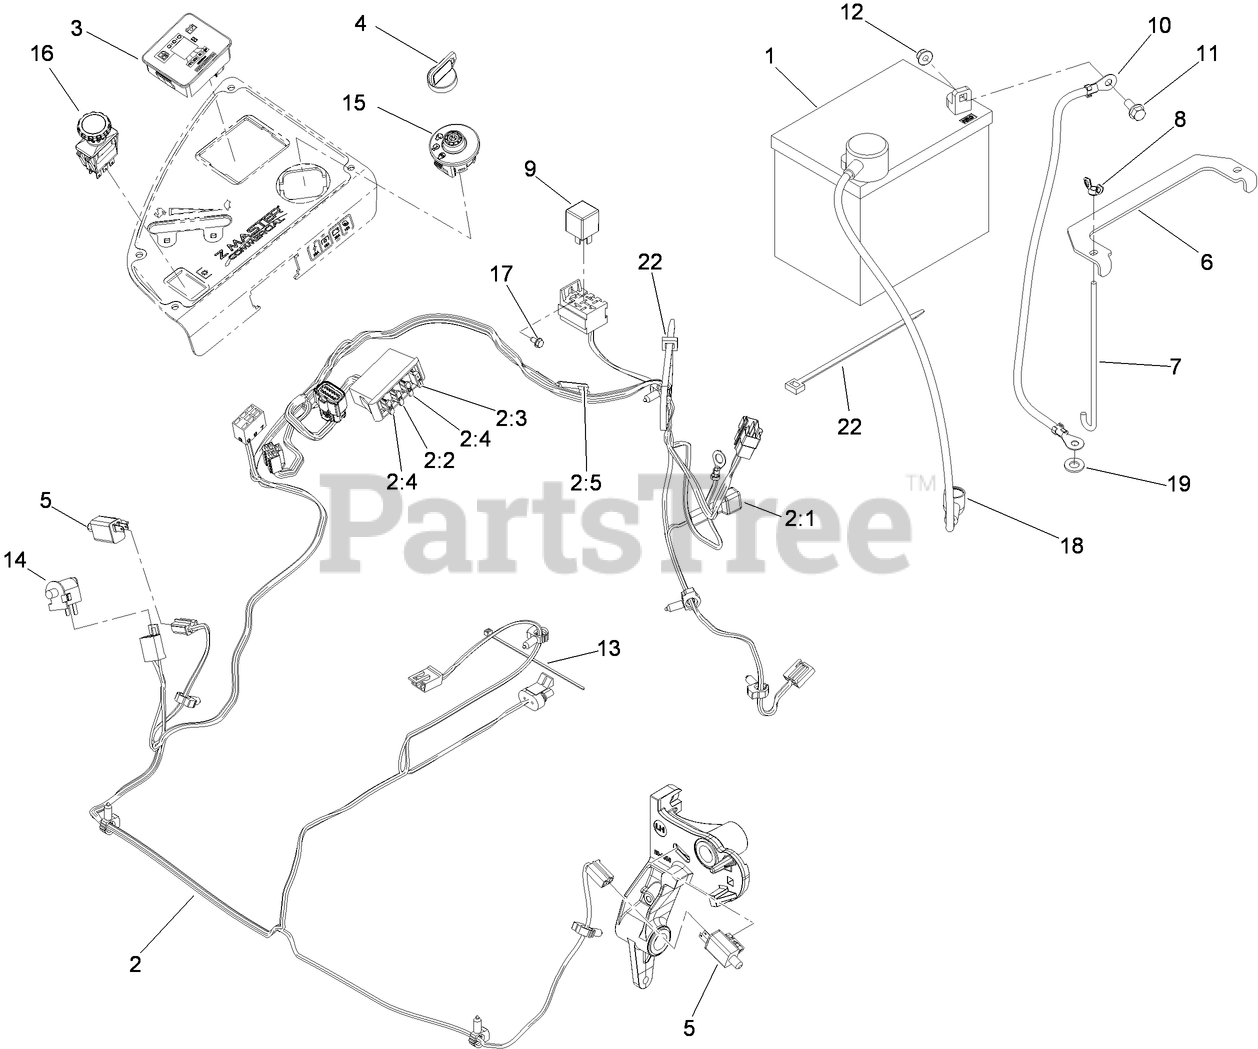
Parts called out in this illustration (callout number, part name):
1	BATTERY
2	HARNESS-WIRE, MAIN
2:2	FUSE-BLADE, 10 AMP
2:3	FUSE-BLADE, 15 AMP
2:4	FUSE-BLADE, 25 AMP
2:5	CAP-PLUG
3	FUEL/HOUR METER ASM
4	KEY-IGNITION
5	SWITCH
6	STRAP-TIE DOWN, BATTERY
7	BOLT-HOLDDOWN
8	WINGNUT
10	CABLE-BATTERY, NEGATIVE
11	SCREW-HHF
12	NUT-HF, NI
13	TIE-CABLE
14	SWITCH-BAIL
15	SWITCH-IGNITION
16	SWITCH-PTO, 10 AMP
17	SCREW-HWH
18	CABLE-BATTERY, POSITIVE
19	WASHER-FLAT
22	TIE-PLASTIC
